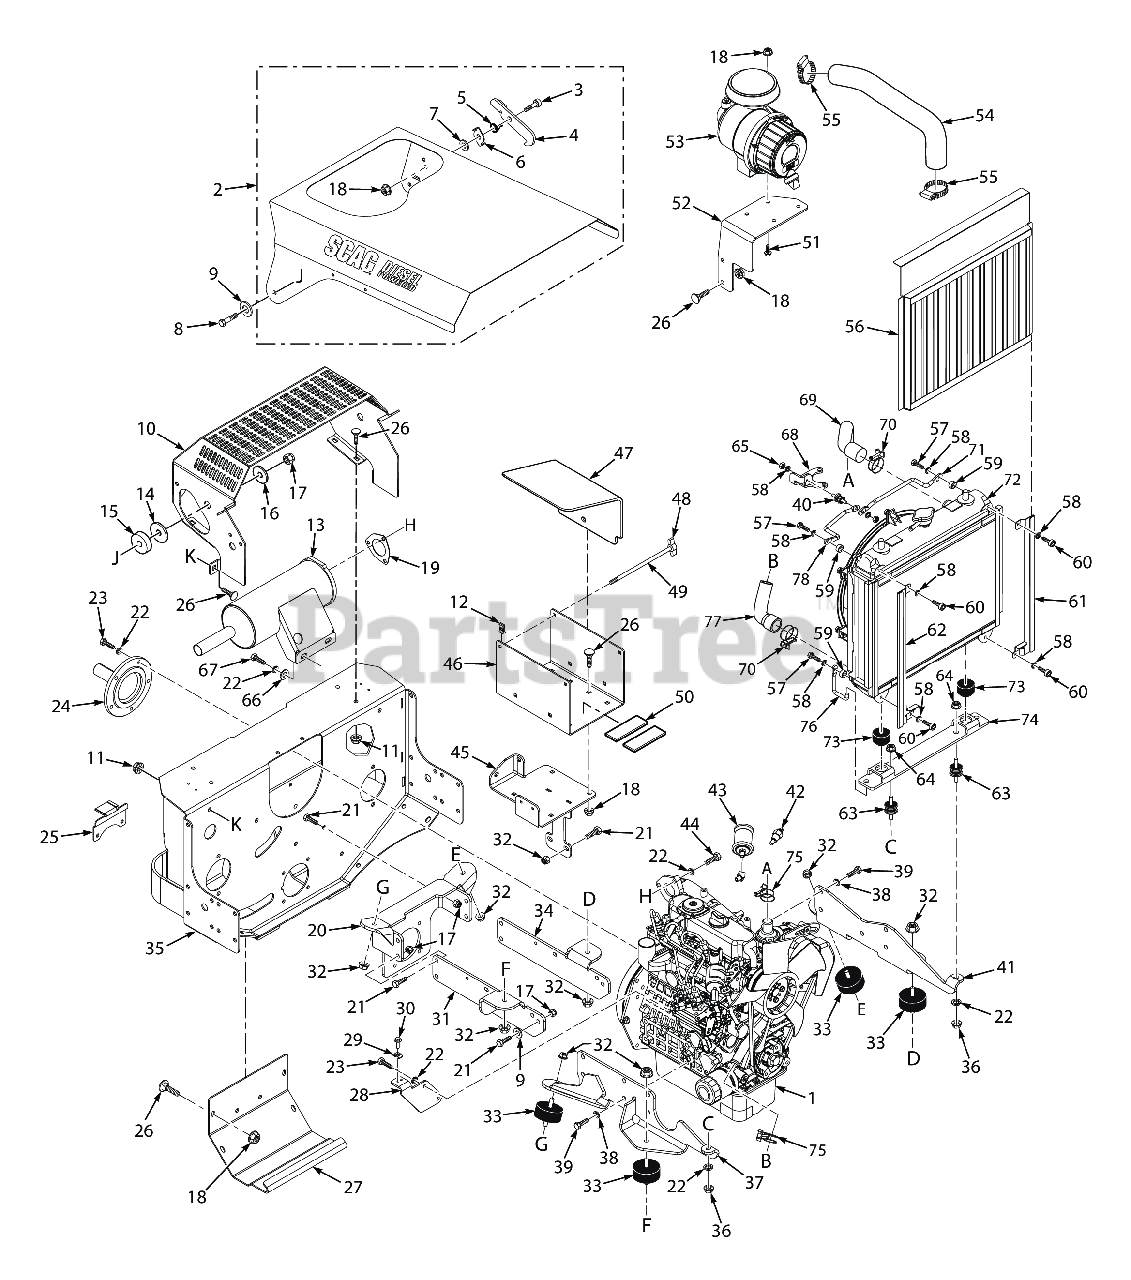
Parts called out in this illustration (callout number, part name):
1	Engine, D902 - Kubota
2	Hood Assy., STTII (Kubota Diesel)
3	Bolt, Shoulder 5/16-18 x 1/2"
4	Latch, Hood
5	Spring, Hood Latch
6	Lock, Hood Latch
7	Flatwasher, 3/8 (.406 x .812 x .065)
8	Bolt, Hex Head 3/8-16 x 1-3/4" (Kohler EFI)
9	Flatwasher, 3/8" Special (.391 x .938 x .105)
10	Guard, Muffler
11	Nut, Flange Head Elastic Stop 5/16-18
12	Bolt, Hex Head 3/8-16 x 1"
13	Muffler, Kubota
14	Disc, Anti-Friction
15	Spacer, Hood
16	Flatwasher, 3/8-.406 x 1-1-1/2 x 7 Gauge
17	HEX NUT, ELASTIC STOP LOCK, 3/8-16
18	Nut, Serrated Flange 5/16-18 (Right Front Engine Mounting, Briggs and Kohler Only)
19	Gasket, Muffler
20	Plate, Rear Engine Mount
21	Bolt, Hex Head, 3/8-16 x 1 Gr. 5
22	Lockwasher, 5/16 (.317 x .586 x .078) Helical Spring
23	Bolt, Metric Hex Head M8-1.25 x 20LG
24	Stub Shaft, (Kubota)
25	Bracket, Belt Guide
26	Bolt, 5/16-18 x .75 RHSN Carriage
27	Cover, Rear
28	Bracket, Control Mount
29	Clamp
30	SCREW, 10-32 X 3/4" SELF TAP
31	Plate, Engine Mount RH
32	NUT, 3/8-16 SERRATED FLANGE HEX HEAD
33	Mount, Engine Isolation
34	Plate, Engine Mount LH
35	Pump Mounting Plate Weldment (Diesel)
36	Nut, Metric Hex M8-1.25mm
37	Mounting Bracket Weldment RH
38	Lockwasher, 7/16� Spring
39	Bolt, Metric Hex Head M10-1.25 x 25LG
40	ISO Mount, Upper Radiator
41	Mounting Bracket Weldment LH
42	Temperature Sensor, Engine Coolant
43	Sender Unit, Oil Pressure
44	Bolt, Metric Hex Head M8-1.25 x 30LG
45	Battery Bracket Weldment (Diesel Only)
46	Battery Box w/Decal (Diesel Only)
47	Cover, Battery (Diesel Only)
47	Insulation, Battery Cover
48	Knob, 1/4" Wing
49	Bolt, Hex Head 1/4-20 x 8"
50	PAD, BATTERY SUPPORT
51	Cpscrw, 5/16-18 x 1"Serrated Flange Hex Head
52	Bracket, Air Cleaner Mount
53	Air Filter Assembly (Enginaire p/n 67150)
54	Hose, Air Intake
55	Clamp, 2-3/4" Max. Dia.
56	Debris Screen Assembly (With Upper Foam)
57	Bolt, Metric Hex Hd. M6-1.0 x 30mm
58	Lockwasher, 1/4� Spring
59	Spacer, Radiator
60	Capscrew, Metric M6-1.0 x 16mm
61	Debris Screen Track RH
62	Debris Screen Track LH
63	ISO Mount, Lower Radiator
64	Nut, Metric Serr. Flng. M8 x 1.25
65	Nut, Metric Hex M6 x 1
66	Flatwasher, 5/16-.344 x .688 x .065 (48V / 52V)
67	Bolt, Metric Hex Head M8-1.25 x 25LG
